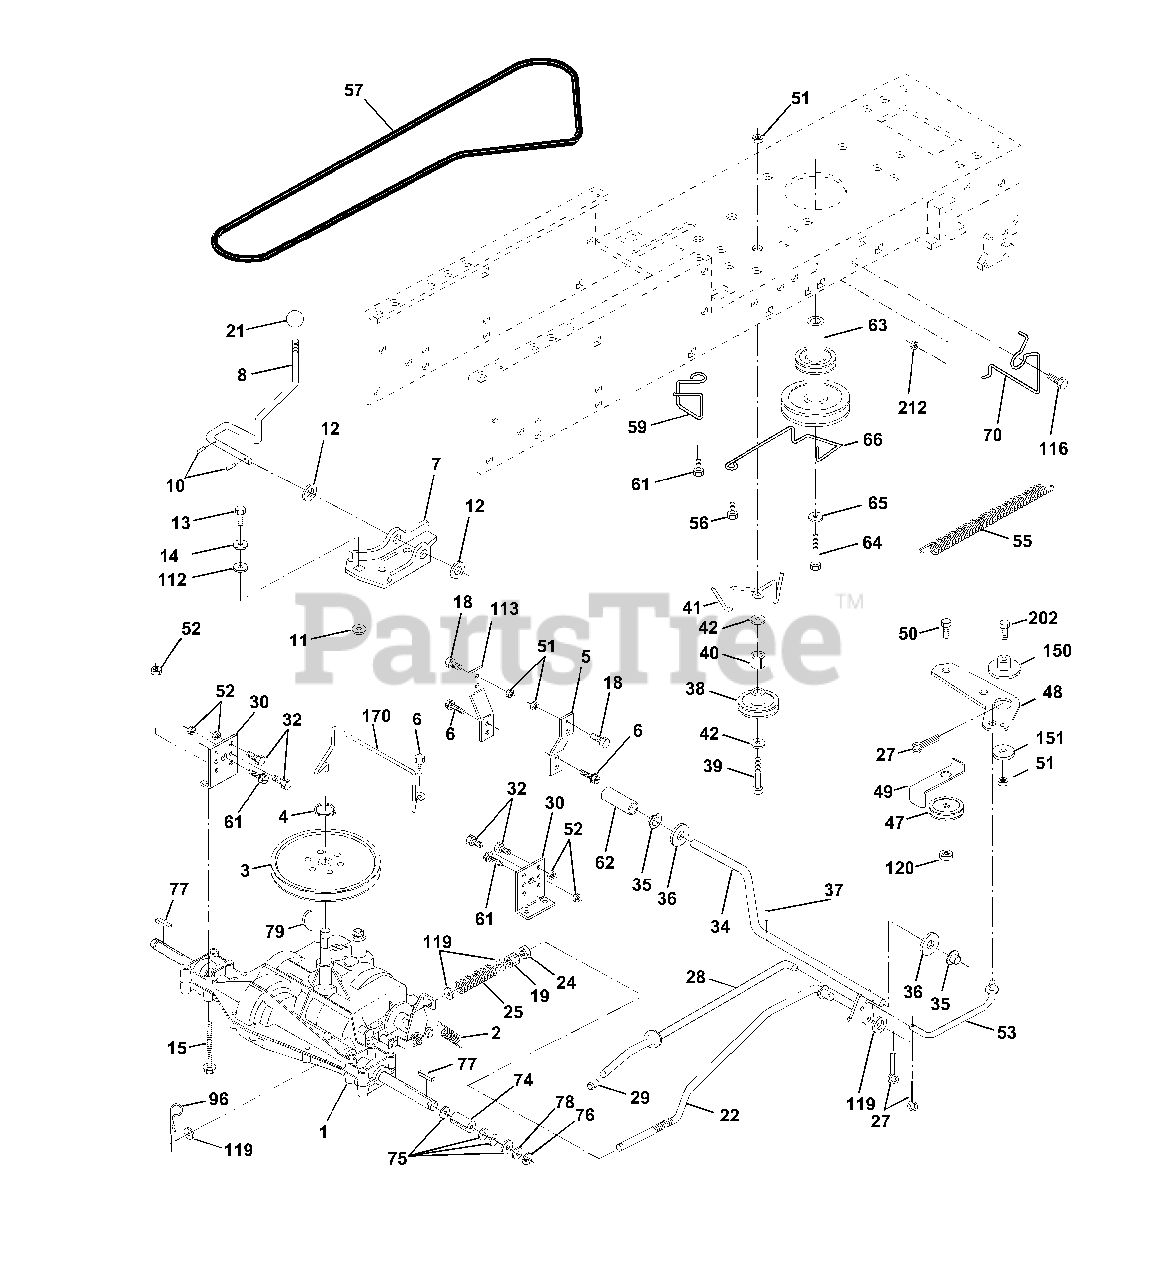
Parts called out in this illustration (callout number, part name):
2	Spring Return Brake T/a Zinc
3	Pulley Transaxle 18/20" tires
4	Ring Retainer # 5100-62
5	Strap Torque 30 Degrees
6	Screw 5/16-18 x 3/4
7	Bracket Saddle Shift T/a
8	Rod Shf Sdl LY/YT Str Blk
10	Pin Cotter 1/8 x 1 Cad
11	Washer Plate 388 Sq Hole
12	Washer 15/32 x 3/4 x 16ga
13	Bolt 1/4-28unf Gr8 W/Patch
14	Washer Lock Hvy Helical 1/4
15	Bolt Hex Flghd 5/16-18 x Gr. 5
18	Bolt Fin Hex 3/8-16 UNC x 1 Gr. 5
19	Nut Lock Hex W/Ins. 3/8-16 Unc
21	Knob Rd 1/2-13 Plstc Thds
22	Rod Brake Blk Zinc 26 840
24	Nut Hex Jam 3/8-16 Unc
25	Spring Rod Brake 2 00 Zinc
27	Pin Cotter 1/8 x 3/4 Cad
28	Rod Brake Parking Lt/Yt
29	Cap Brake Parking
30	Bracket Mtg Transaxle
32	Bolt Hex Hd 5/16-18unc x 3/4
34	Shaft Asm Pedal Foot Nibbed
35	Bearing Nylon Blk 629 Id
36	Washer 21/32 x 1 x 16 Ga
37	Pin Roll 3/16 x 1"
38	Pulley Composite Flat
39	Bolt Fin Hex 3/8-16 UNC x 3 Gr. 5
40	Spacer Split 395 x 59 Bzp
41	Keeper Belt Idler
42	Washer 13/32 x 13/16 x 12 Ga
47	Pulley Idler V Groove Plastic
48	Bellcrank Asm. Clutch
49	Retainer Belt Style Spring
50	Bolt Hex Hd 3/8-16unc x1-1/2
51	Nut Crownlock 3/8-16 UNC
52	Nut Crown Lock 5/16-18
53	Link Clutch 7 66
55	Spring Return Clutch 6 75
56	Screw 3/8-16 x 1
57	V-Belt Gd Drive 9530
59	Keeper Belt Centerspan
61	Screw 3/8-16 x 3/4
62	Cover Pedal Blk Round
63	Pulley Eng Cl Cable
64	Bolt Hex 7/16-20 x 4 Gr 5
65	Washer Lock Hlcl Spr 7/16
66	Keeper Belt Engine FP
70	Guide Belt Mower Drive RH
74	Spacer Axle
75	Washer 25/32 x 1-1/4 x16 Ga
76	E-ring #5133-75
77	Key Square 2 0 x 1845/ 1865
78	Washer 25/32 x1-5/8 x 16 Ga
79	Key Woodruff #9 3/16 x 3/4
96	Retainer Spring 1
112	Washer 9/32 x 3/4 x 10 Ga
113	Strap Torque LH LT
116	Bolt 3/8-16 x 1
119	Washer 13/32 x 5/8 x 16 Ga
120	Nut Lock Flg 3/8-16
150	Spacer Retainer
151	Washer 13/32 x 2 x 10 Ga.
170	Keeper Belt Transaxle Gear
202	Bolt Carr. Sh 3/8-16 x 1-3/4 Gr. 5
212	Nut Hex Flange Lock
